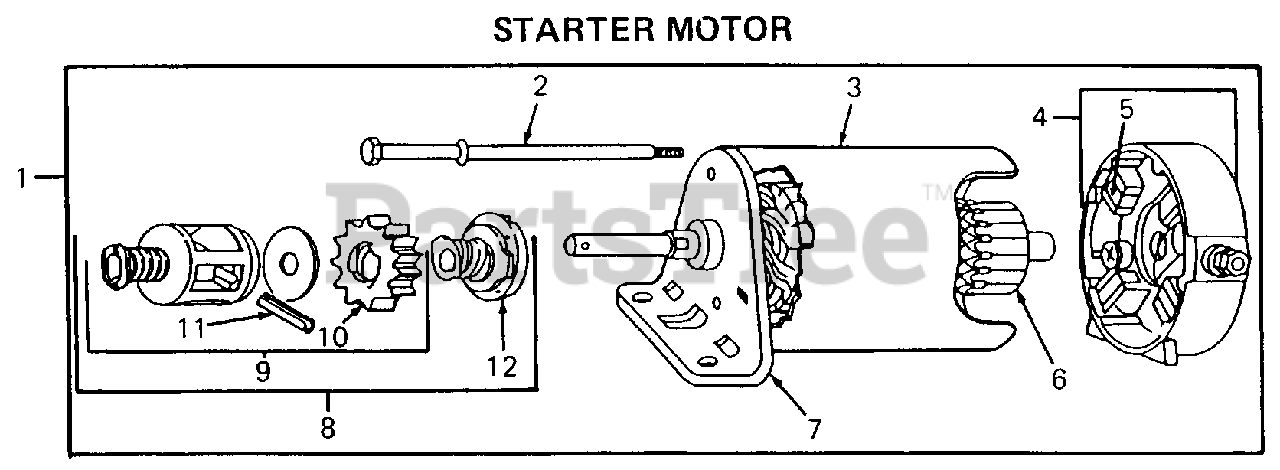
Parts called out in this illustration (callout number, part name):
1	Motor & Drive Assy
3	Housing Assy
4	End Cap Assy
5	Brush Assy
6	Armature Assy
7	End Cap Assy
8	Drive Assy
9	Retainer Kit
10	Gear
11	Pin, Roll
12	Clutch Assy
